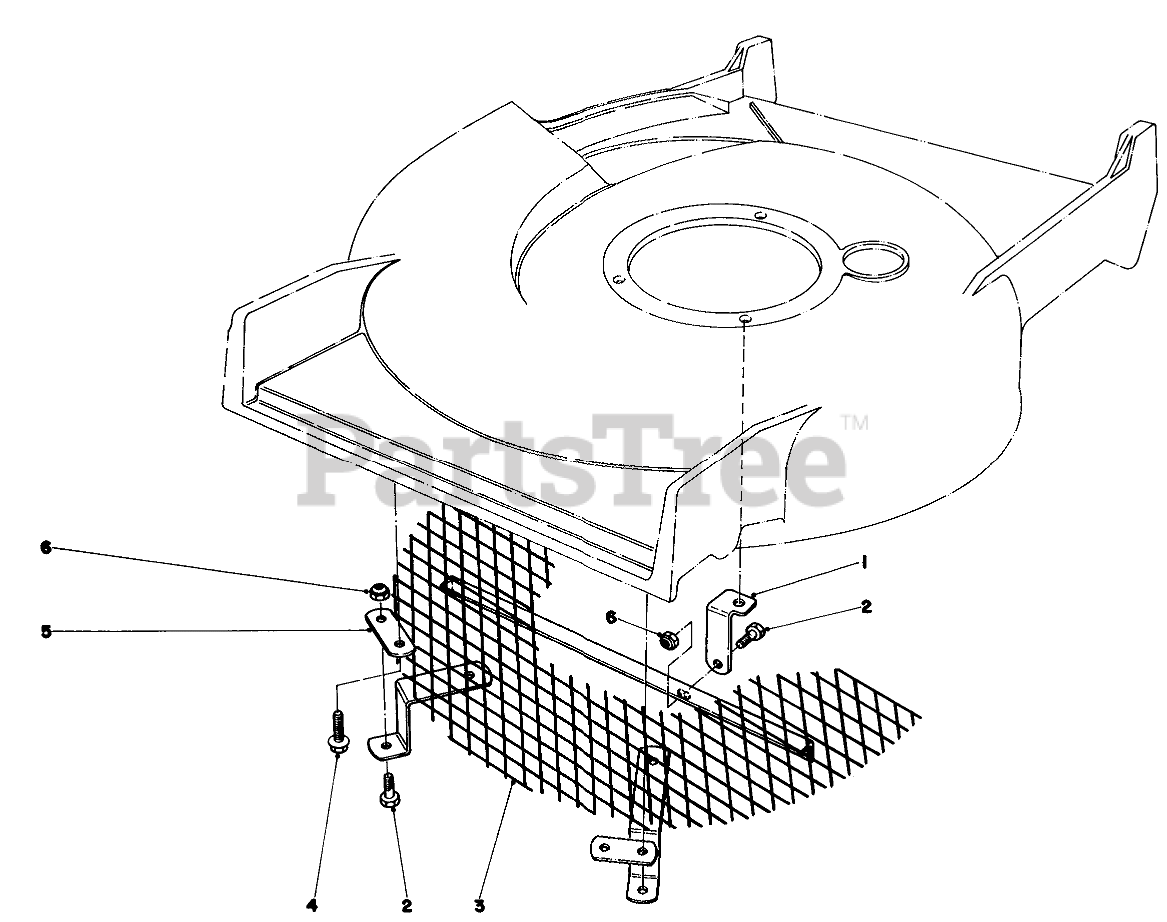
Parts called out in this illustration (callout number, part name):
1	Support Bracket
2	SCREW-HH
3	Screen
4	SCREW-HWHTF
5	ANCHOR
6	NUT-LOCK, NI
